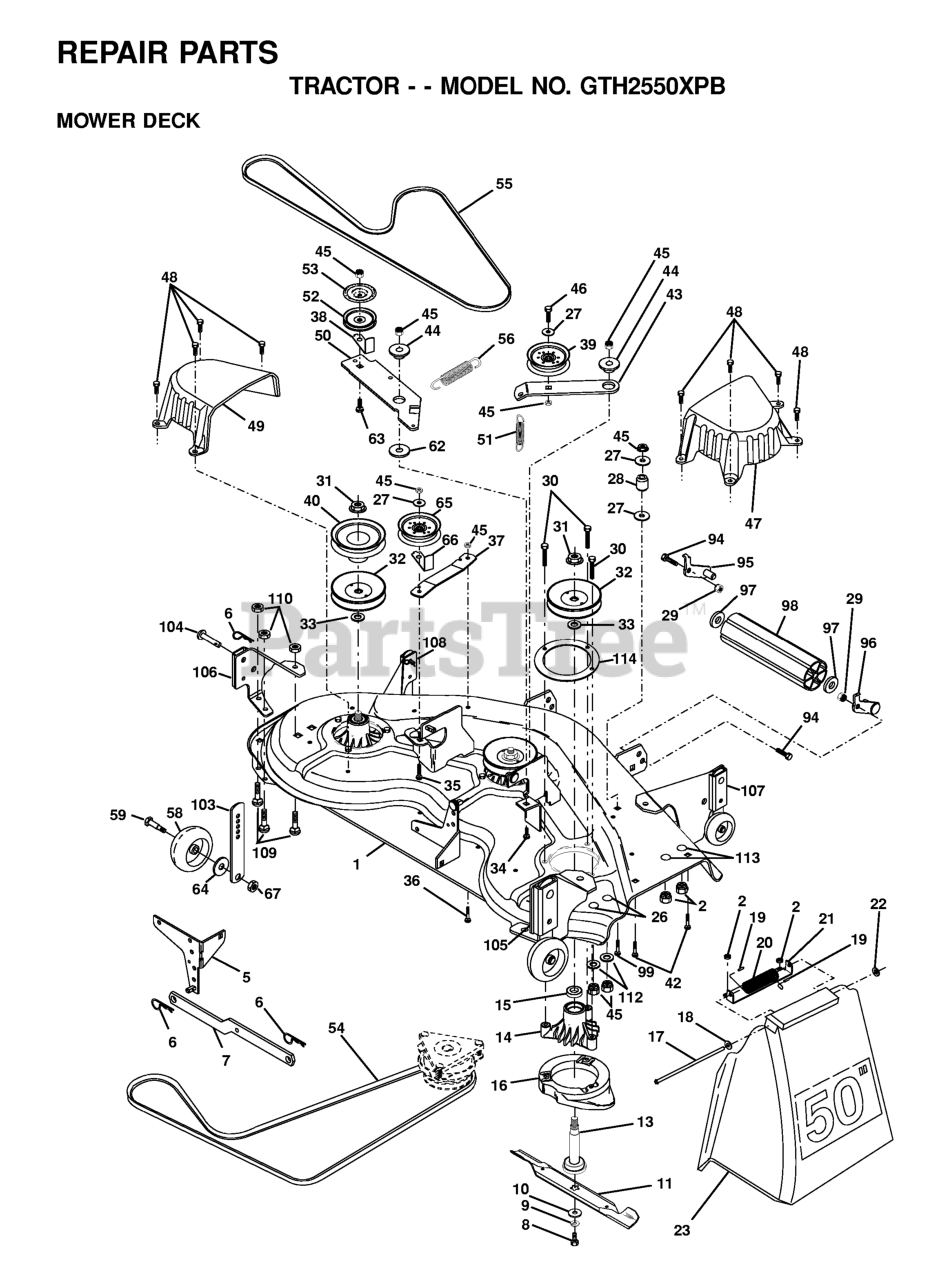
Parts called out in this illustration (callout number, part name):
2	LOCKNUT
5	BRACKET SWAY BAR
6	RETAINER-SPRNG RB
7	REAR SUSP ARM
8	BLADE BOLT
9	LOCKWASHER
10	WASHER.BLADE
11	BLADE.50".HI-LIFT
13	SHAFT.ASM.W/BEARING
14	HOUSING.MANDREL.44/46" VENT
16	STRIPPER.MANDREL.ROUND.BLACK
17	ROD-HINGE T
18	Washer 11/32 x 5/8 x 16 Ga SD
19	CAP-SLEEVE LT
20	SPRING TORSION
21	BRACKET, DEFLECTOR
22	NUT PUSH M
27	WASHER
28	IDLER SPRING SPACER
29	NUT.71038.31-18.HEX.NYLOCK
30	SCREW THDROL ROLLING WASHER HD
31	NUT
32	PULLEY MANDREL
33	WASHER
34	BOLT.3/8-14X1.25
36	BOLT D
37	STIFFENER ARM
38	KEEPER.BELT.IDLER.PLATED
39	PULLEY.IDLER.FLAT
42	RP BOLT 5/16-18 X3/4 ZN/YEL GR
43	ARM.IDLER.SEC.44"
44	SPACER RETAINER
46	BOLT
47	COVER MANDRELL
48	SCREW.1/4-20X5/8
49	COVER.MANDREL.LH.44"
50	ARM.IDLER.PRIMARY
51	SPRING.SEC.44"VEN
52	PULLEY IDLER
53	SHIELD IDLER
54	V-BELT.PRMRY 46/50 VENT.BLK BK
55	BELT V SECONDARY
58	WHEEL GAGE DONUT
59	BOLT, SHOULDER
62	HARDENED WASHER
63	BOLT.3/8-16X1.50
64	WASHER.5/16.FLAT.STE.STD.
66	KEEPER BELT IDLER PLATED
67	LOCKNUT
94	BOLT RB
95	BRACKET ASM, ROLLER (L)
96	BRACKET ASM, ROLLER
97	Washer 1 17/32 X 7/8 X 16 Ga
98	NOSE ROLLER
103	BAR.ADJUST.WHEEL.ANTI.SCALP.BL
104	RIVET.PIN.HEAD.YELLOW.
112	WASHER
113	BOLT.CARR.5/16-18X1/2
